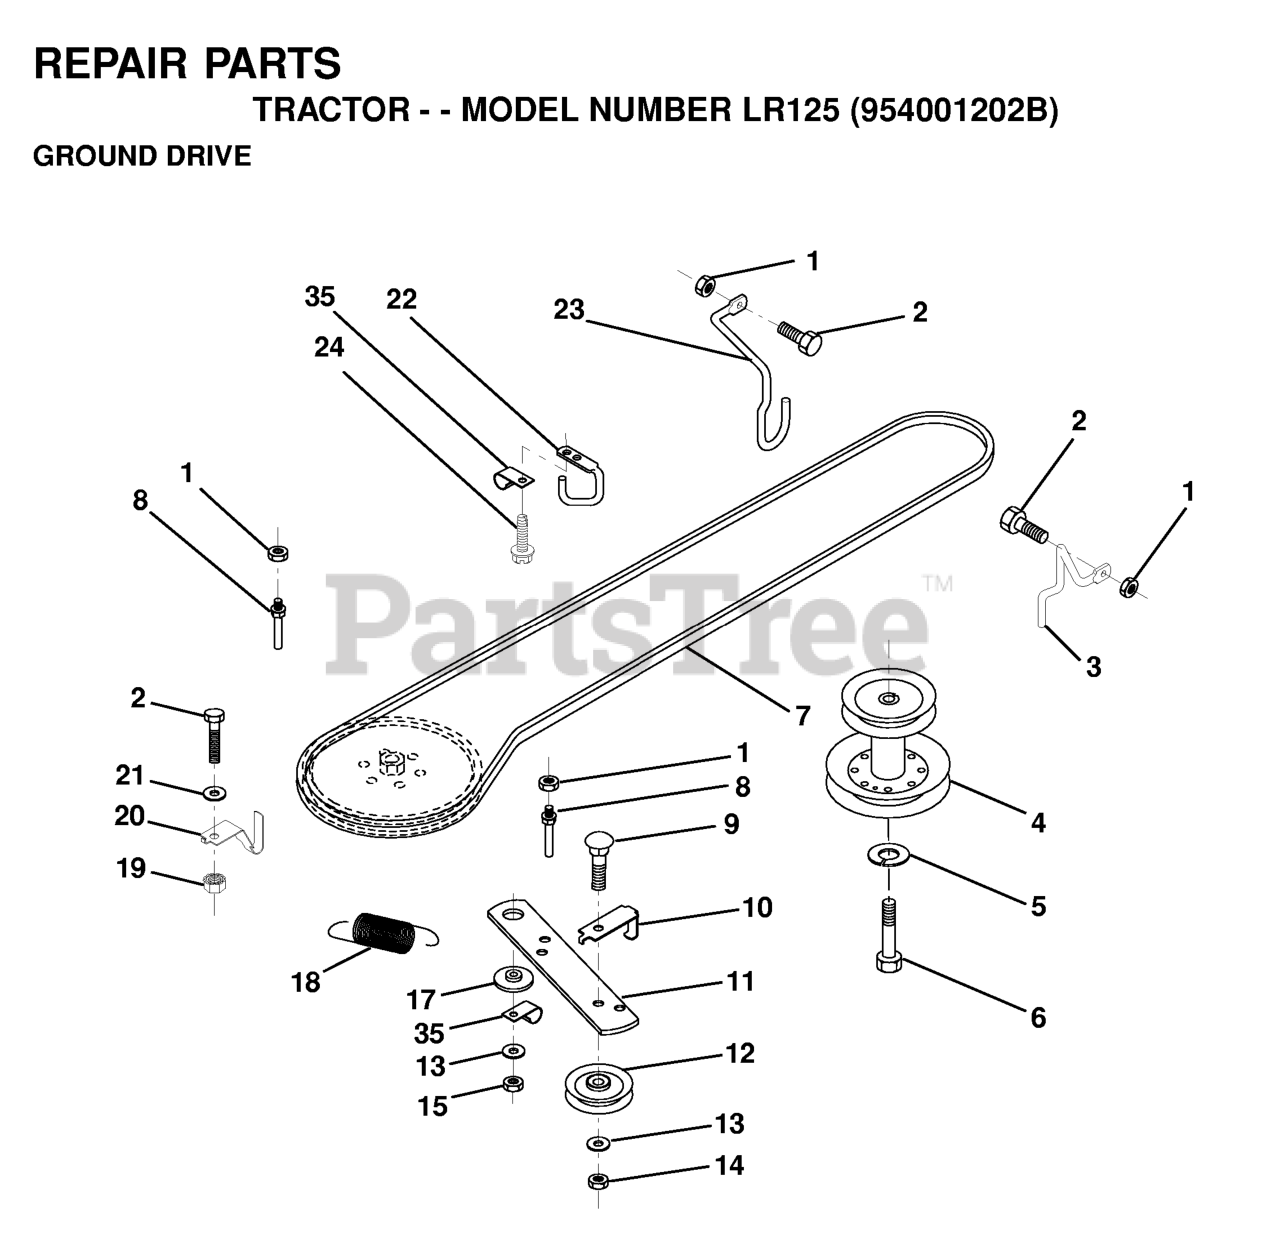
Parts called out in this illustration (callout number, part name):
1	LOCKNUT
2	BOLT
3	KEEPER.BELT.FRT.
4	PULLEY.ENGINE.36/38 LR
5	LOCKWASHER
8	KEEPER,DRIVE BELT
9	Bolt, Carriage 3/8-16 UNC x 1-1/2
10	KEEPER.BELT.GROUND.DRIVE.IDLER
11	ARM/GROUND DRIVE CLUTCH
12	PULLEY.IDLER.FLAT
13	WASHER
14	LOCKNUT
17	SPACER RETAINER
18	SPRING.EXTENSION
19	NUT
20	KEEPER-T/A GROUND DRIVE BELT
21	Washer 11/32 x 5/8 x 16 Ga SD
22	KEEPER,FRA DR BEL
23	KEEPER BELT LH FR
24	SCREW
35	CLIP INSULATOR
